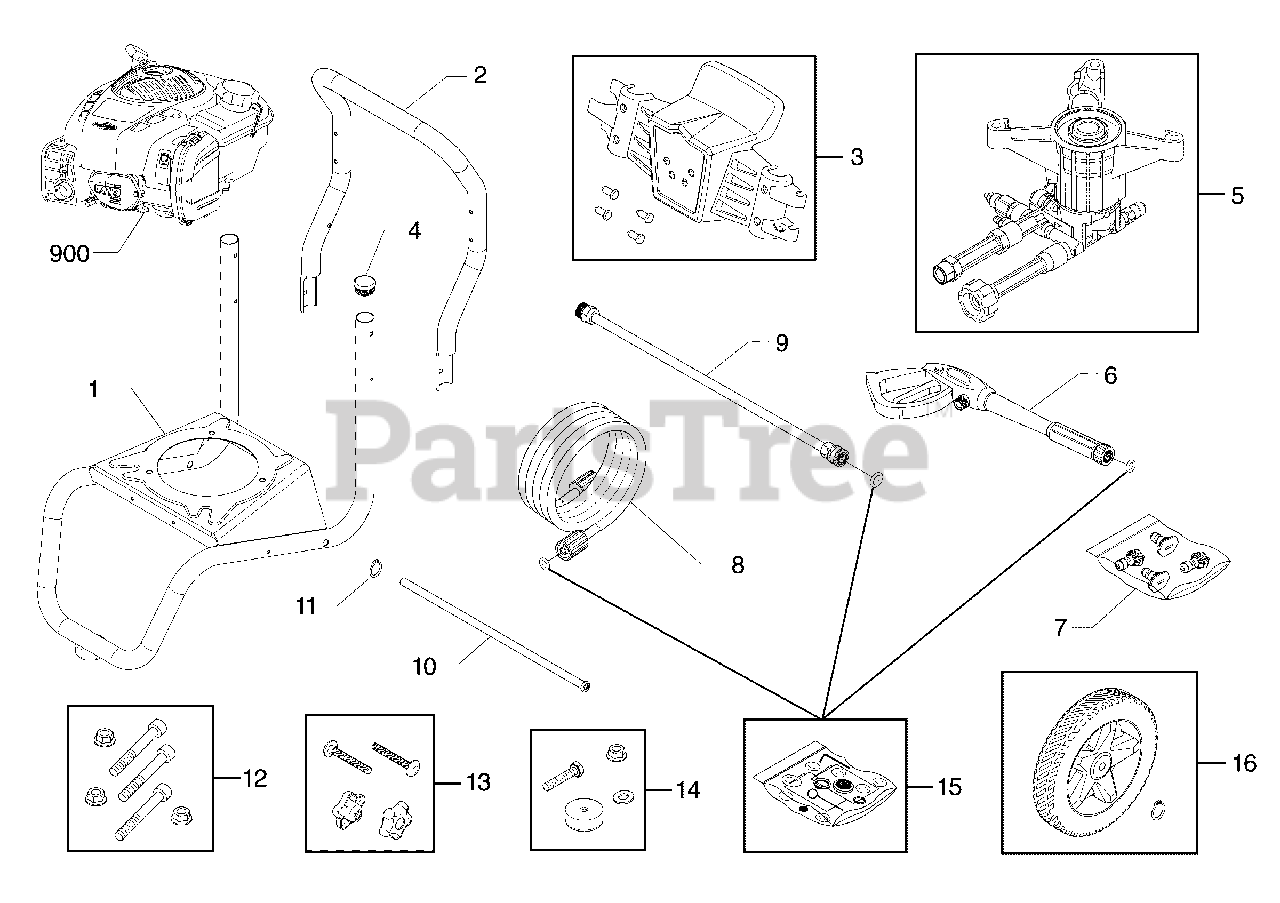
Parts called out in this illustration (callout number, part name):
6	GUN
7	KIT-QC NOZZLES
8	HOSE
9	EXTENSION, QC
12	KIT, Hardware, Pump Mounting
13	KIT, Hardware, Handle
14	MOUNT, Vibration
